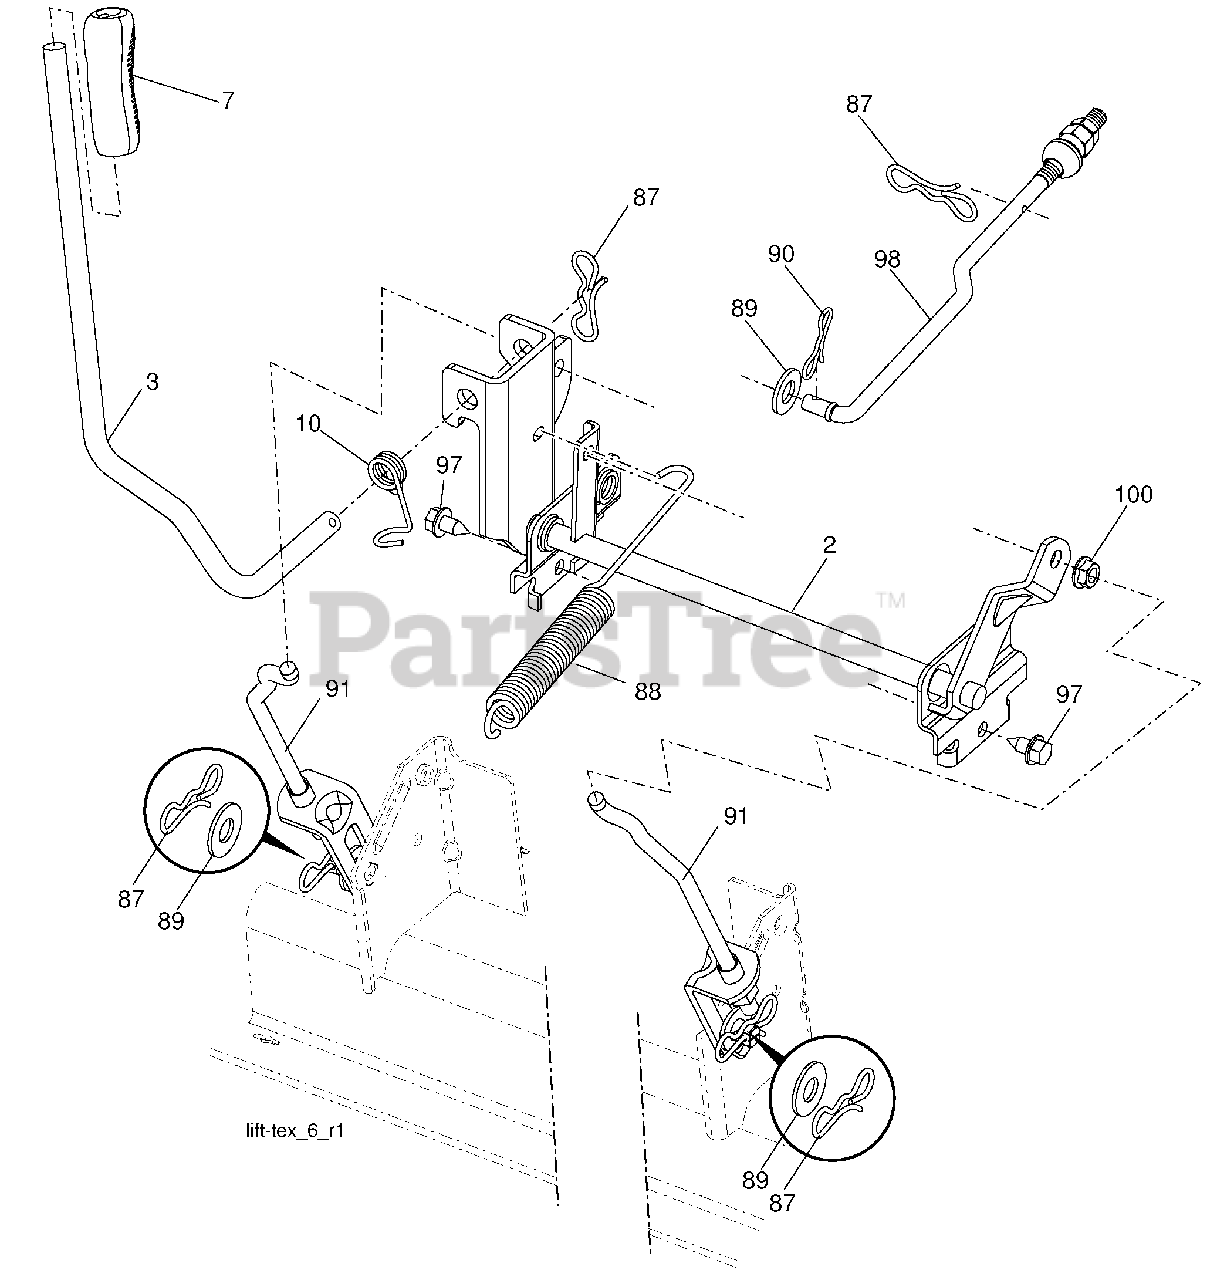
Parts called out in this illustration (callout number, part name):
2	Shaft Asm., Lift
3	Lever Asm., Lift RH
7	Grip, Lever
10	Spring Torsion
87	Pin Cotter 7/16 Bow Tie Lock
88	Spring Lift Assist
89	Washer Clear Zinc
90	Pin Cotter 5/16 Bow Tie Lock
91	Link Lift Susp Mower Rear
97	Screw 3/8-16 x .75 Smgml Tap/R.Z
98	Link Lift Susp. Front Mower
100	Nut Centerlock 3/8 -16 unc
